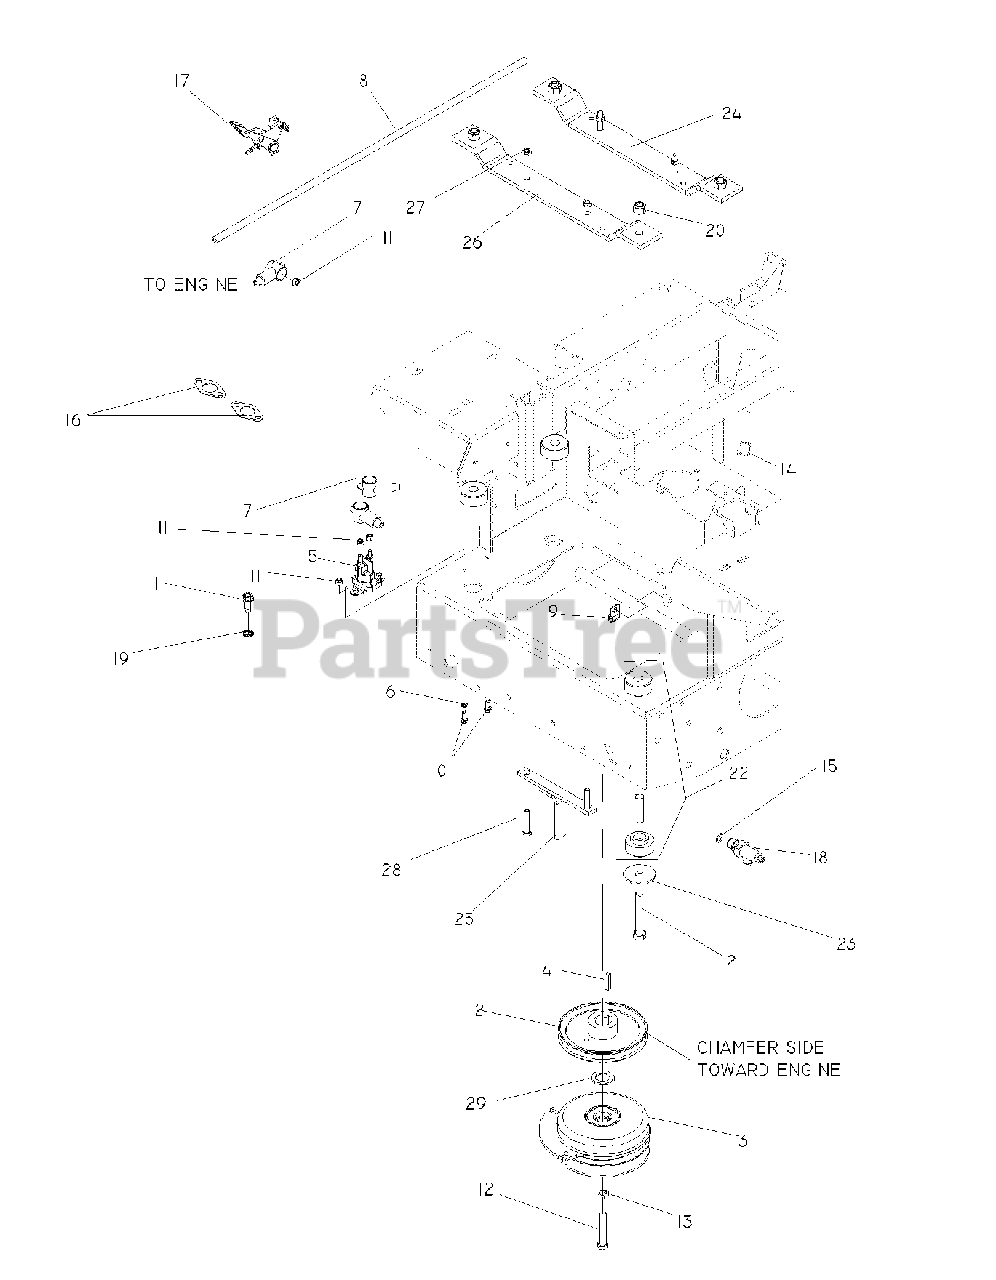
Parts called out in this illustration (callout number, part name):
1	BOLT 3/8-16 X 1.0
3	CLUTCH-200 FT LB(RPLS 5218-102
4	KEY, 1/4 SQ X 1 1/4
5	SOLENOID
6	WASHER 1/4 INT TOOTH
7	INSULATOR
8	FUEL LINE 29.5"
9	DOUBLE TUBE CLAMP
10	HCS 1/4C X 5/8
11	NUT 1/4-20 NYLOC
12	BOLT 7/16F X 2 1/2
13	WASHER 7/16 LOCK
14	TIE, PLASTIC
16	EXHAUST GASKET - KAW
17	CABLE CHOKE
18	VALVE ASSEMBLY
19	WASHER 3/8 EXT STAR ZD
20	NUT 1/2-13 HEX NYLOC ZD
21	HCS 1/2C X 3 1/4
22	ISOLATORS
23	ISOLATOR WASHER
24	ENGINE MOUNT
25	CLUTCH TIE DOWN
26	STRAP, ISO, REAR
27	NUT 5/16C CENTERLOCK
28	HCS 5/16-18 X 1-3/4 SERATED
29	BUSHING, 10GA MACHINERY
